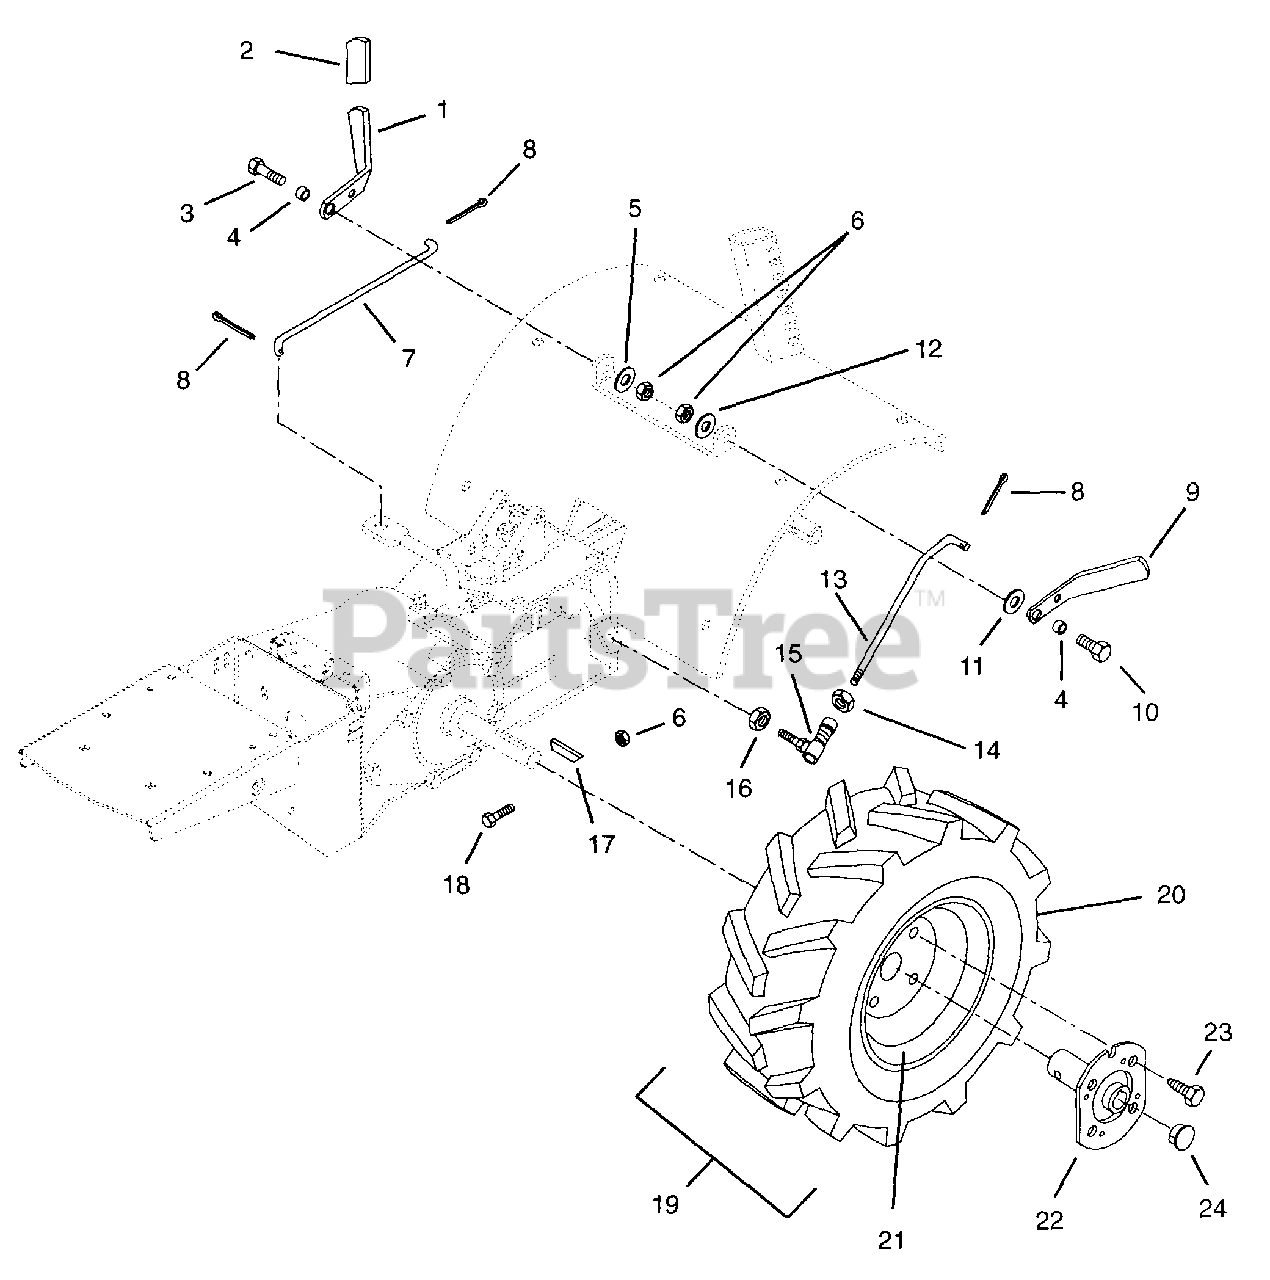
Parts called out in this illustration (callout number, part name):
1	DRIVE CLUTCH HANDLE
3	@BLT-HEX .31-18X1.25 GR5 YWZC
4	SPACER BUSHING .5 X .32 X .21
5	@WSHR-FL-STL.38X.875X.083 YWZC
6	@NUT-LK-CTR .31-18 YWZC
7	DRIVE CLUTCH ROD
8	@PIN-CTR .09X.75 EXTPRSQCT YWZ
9	TILLER CLUTCH HANDLE
10	@BLT-HEX .31-18X.75 GR5 YWZC
11	SPACER .344X1.000X.375
12	WSHR-FL-STL .344X1.375X.075YWZ
13	TILLER CLUTCH ROD
14	NUT-HEX .312-24 PL
15	SNAP IN BALL JOINT
16	NUT-CTRLK .31-24 YWZC
17	KEY-FTHR .25X1.875X.25 SAE
18	@BLT-HEX .31-18X2.00 GR5 YWZC
19	T/WHL ASSY 4.80-8
21	TIRE 4.80-8 NHS
22	WHEEL HUB
23	SCR-TAP .500-20X.62 HH YWZC
24	HOLE PLUG 1.00"
